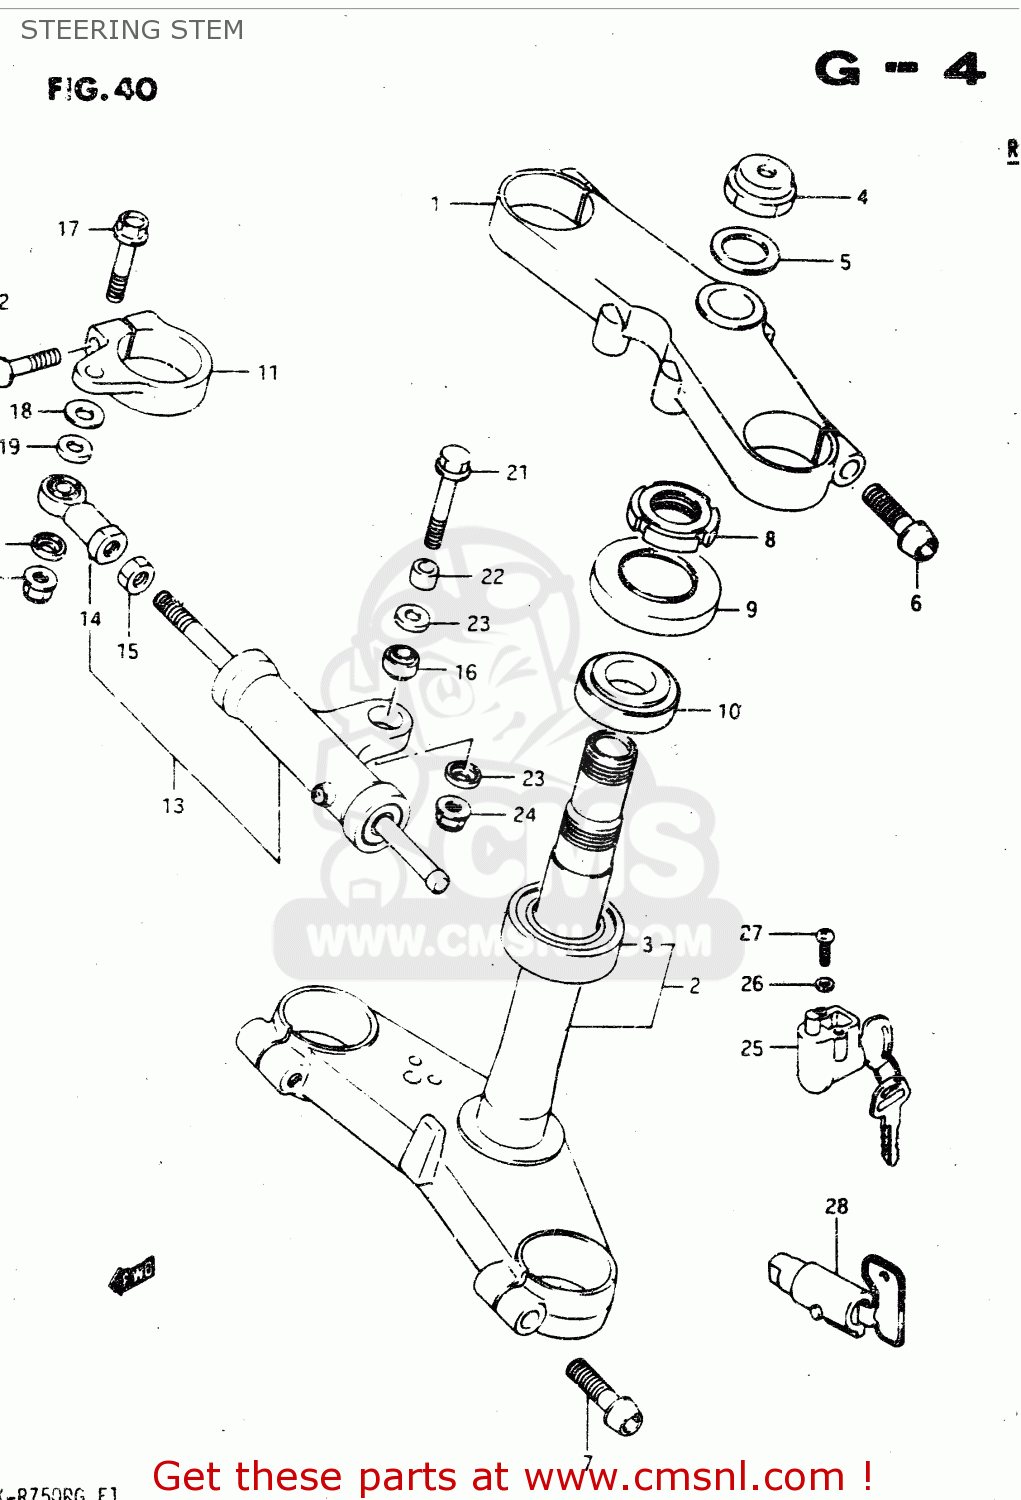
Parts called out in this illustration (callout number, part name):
1	HEAD,STEERING STEM
2	STEM,STEERING
3	BEARING
4	NUT,STEM HEAD
5	WASHER
6	BOLT,UPPER
7	BOLT,FORK INNER TUBE F
8	NUT,STEERING STEM(25X44X10)
9	DUST SEAL,STEERING UPR
10	TAPER,ROLLER BEARING
11	BRACKET,STEERING DAMPER
12	BOLT
13	DAMPER ASSY, STEERING
14	BEARING, LOD END
15	NUT
16	BEARING(8X18X11)
17	BOLT
18	WASHER
19	20
20	NUT
21	BOLT(8X45)
22	SPACER (8.5X15X10)
23	24
24	NUT
25	LOCK ASSY, STEERING
26	LOCK WASHER
27	SCREW 5X20
28	LOCK ASSEMBLY,STEERING (NEI
